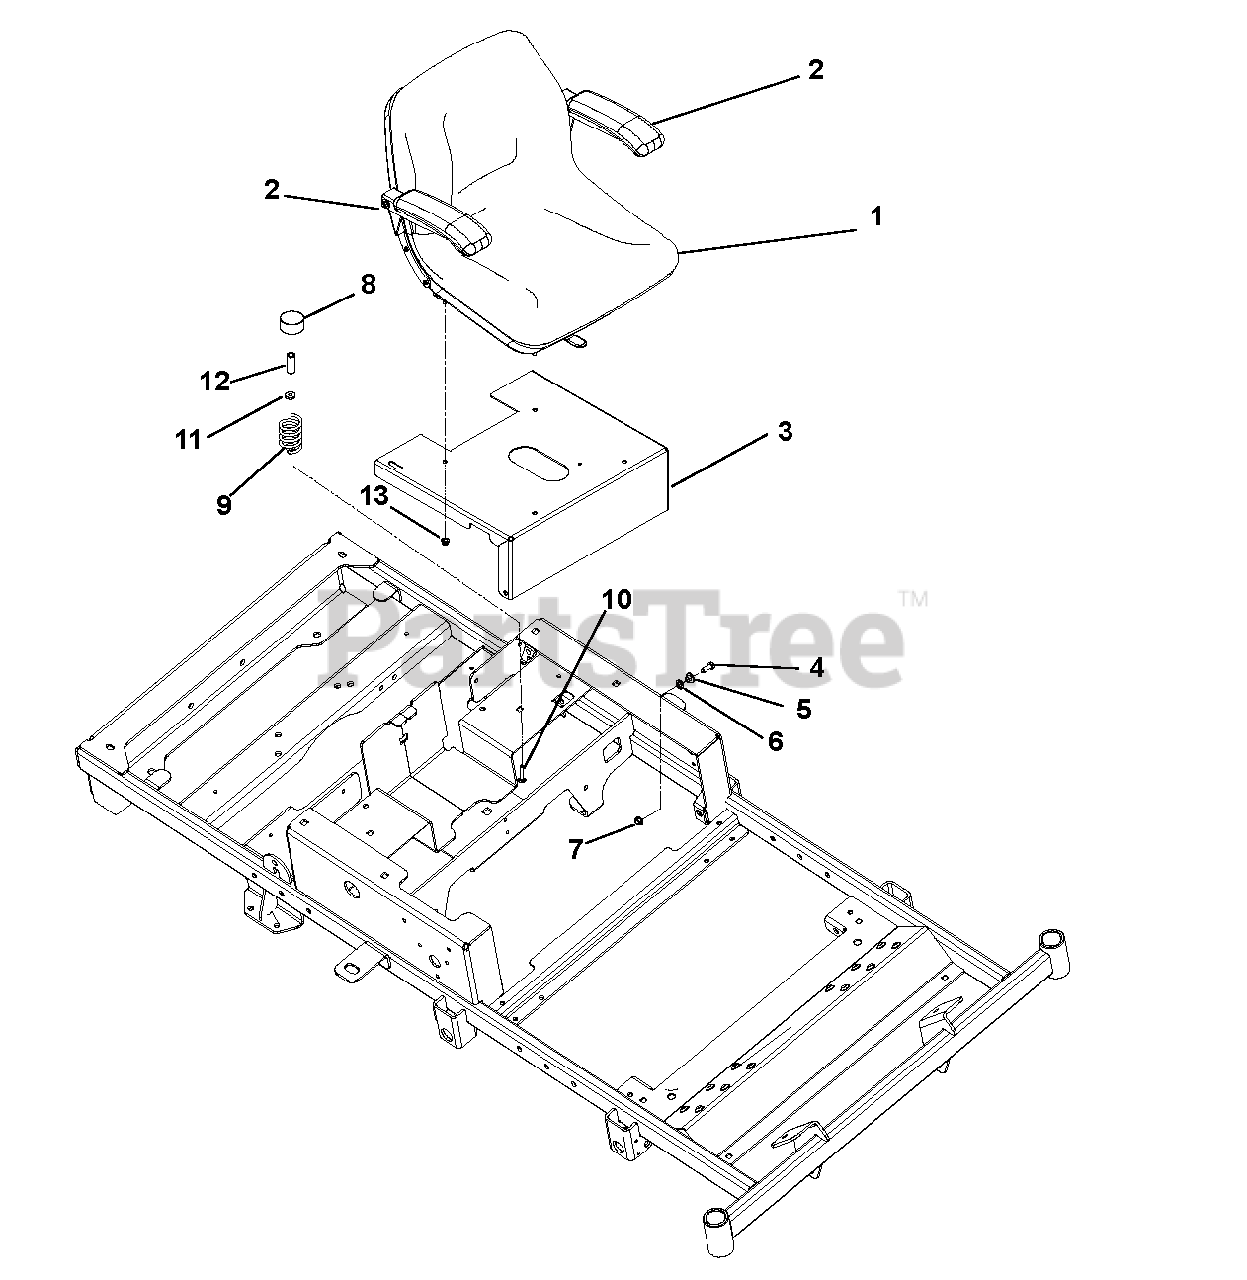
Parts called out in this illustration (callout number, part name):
1	Seat with Arm
2	Arm Rest Kit
3	Seat Plate
4	Bolt, Hex .38-16 x 1.00 Grade 5
5	Bushing, Flange .385 x .500 x .875 x .406
6	Washer, Flat Steel .52 x .827 x .062
7	Nut, .38-16 Nyloc Flange
9	Spring, Seat
10	Bolt, Round Head Square Neck .31-18 x 1.50 Grade 5
11	Washer, Flat Steel .328 x .87 x .179
12	Nut, Coupling 5/16-18 x 1 .75
13	Nut, 5/16-18 Flange Nyloc
